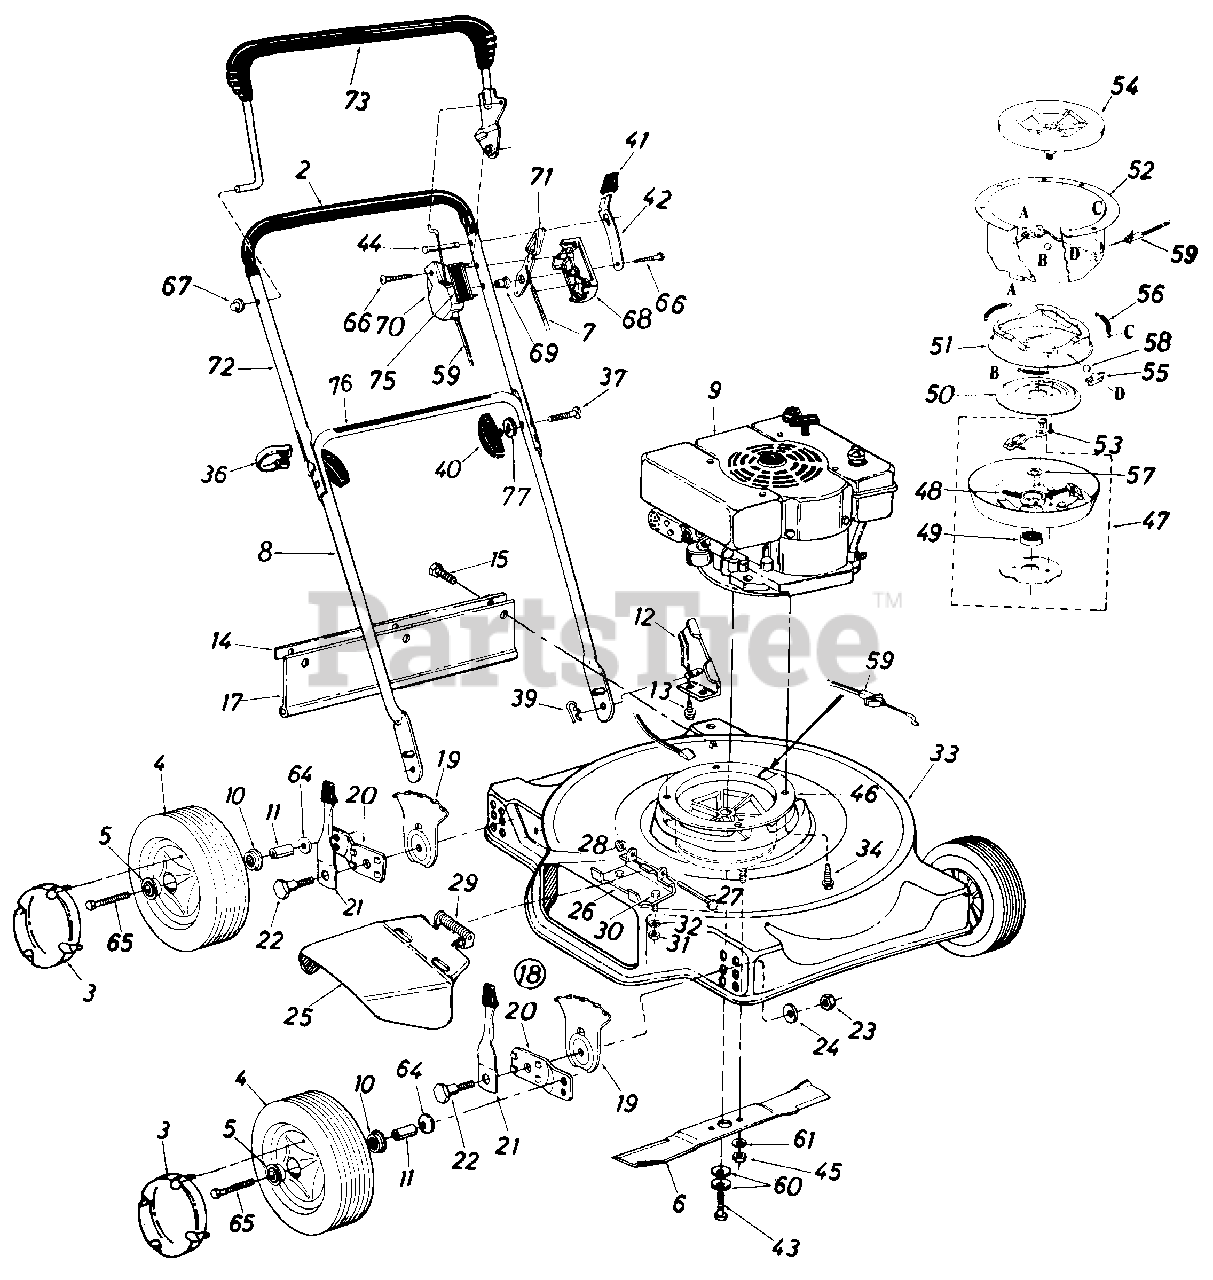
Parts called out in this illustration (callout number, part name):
3	Hub Cap
4	Wheel Ass'y. Comp.
5	Ball Bearing 3/8 I.D.
6	22" Blade
7	Throttle Control Wire 39"
8	Lower Handle
10	Ball Bearing 1/2" I.D.
11	Spacer
12	Handle Mount Brk't. Ass'y. L.H.
13	Hex Wash. Hd. B-Tap Scr. 5/16-18 x .50" Lg.
14	Retaining Strip
15	Hex Wash. Hd. AB-Tap Scr. 1/4" x .62" Lg.
17	Rear Flap Ass'y.
18	Height Adj. Ass'y. R.H.
19	Height Adj. Plate
20	Pivot Bar
21	Spring Lever w/Knob
22	Shld. Bolt .500" Dia. x .375
23	Hex Nut 3/8-16 Thd.
24	Bell-Wash. .39" I.D. x 1.4" O.D.
25	Chute Deflector Ass'y. Comp.
26	Deflector Hinge Plate
27	Pivot Pin
28	Cap Speed Nut 1/4" Rod
29	Torsion Spring
30	Hex Bolt 1/4-20 x .50" Lg.
31	Hex Nut 1/4-20 Thd.
32	L-Wash. 1/4" I.D.
33	22" Deck Ass'y.
34	Hex Wash. Hd. TT-Tap Scr. 3/8-16 x 1.00" Lg.
36	Cable Tie
37	Carriage Bolt 5/16-18 x 1.75" Lg.
39	Hairpin Cotter
40	Hand Knob
41	Spring Lever Knob
42	Lock Out Spri ng
43	Hex Cent. L-Bolt 3/8-24 x 2.00" Lg.
44	Lock Pin .75" Dia. x 1.80
45	Special Hex Nut 5/16-24 Thd.
46	Blade Brake Clutch Ass'y. Comp.
47	Clutch Blade Housing Ass'y.
48	Comp. Spring .35 O.D. x 2.00" Lg.
49	Ball Brg. .669" I.D. x 1.574" O.D.
50	Clutching Cone
51	Brake Cup Cone
52	Clutch Housing
53	Hex Wash. TT-Tap Cl.-Scr. 1/4-20 x .75" Lg.
54	Fan Adapter
55	Ball Block
56	Extension Spring .35" O.D. x 1.75" Lg.
57	Fl-Wash. .690" I.D. x 1.060" O.D.
58	Steel Ball .500" Dia.
59	Clutch Cable 42"
60	Bell-Wash. .400" I.D. x .88" O.D.
61	L-Wash. 3/8" I.D.
64	Bell-Wash. .400" I.D. x .88" O.D.
65	Axle Bolt
66	Truss Mach. Hi-B Tap Scr. #12 x 1.50" Lg.
67	Cap Speed Nut 5/16" Rod
68	Control Panel Half
69	Control Disc Pin
70	Clutch Panel Half
71	Throttle Control Lever
72	Upper Handle
73	Control Handle Ass'y.
75	Control Label Throttle
76	Instruction Label Handle
77	Bell-Wash. 5/16" I.D.
